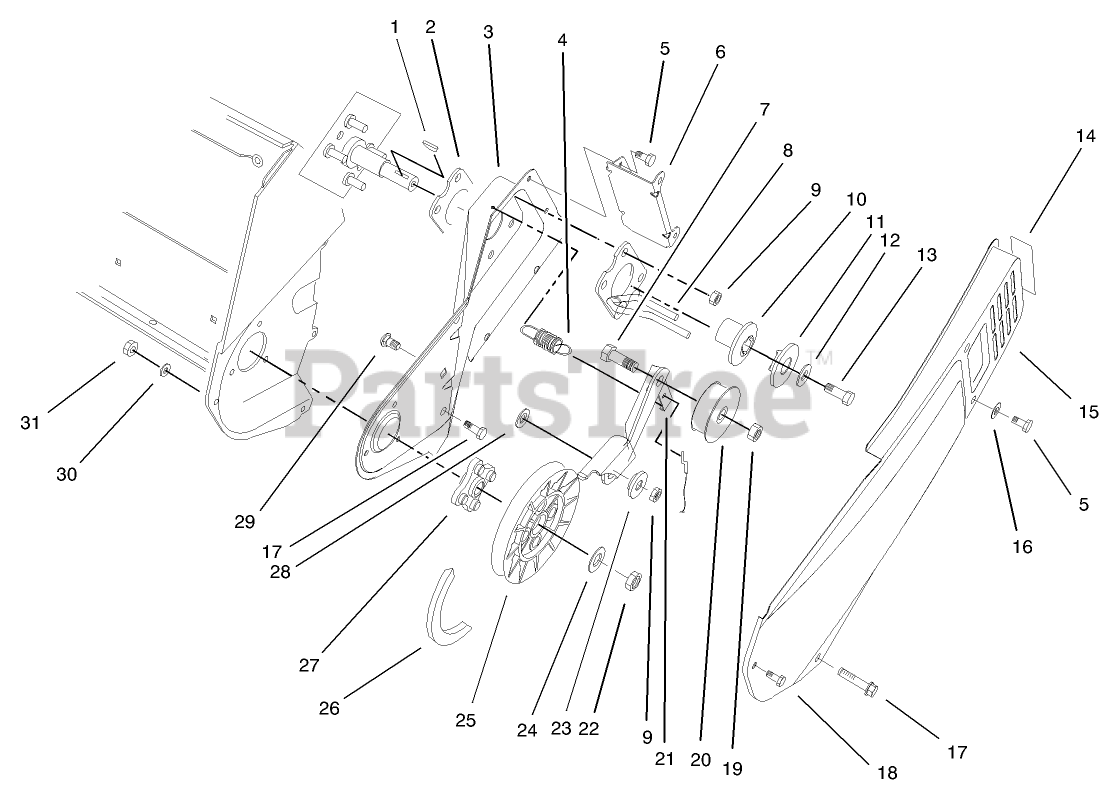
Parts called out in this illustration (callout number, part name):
1	KEY-WOODRUFF
2	PLATE-ENGINE
3	SIDEPLATE-LH
4	SPRING-BRAKE
5	SCREW-HWH
6	BRACKET-COVER, BELT
7	SCREW-HH
8	GUIDE-BELT
9	NUT-LOCK, NI
10	HUB-HALF SHEAVE
11	CAP-HALF SHEAVE
12	WASHER-FLAT
13	SCREW-HH
14	DECAL-HOT
15	COVER-BELT
16	WASHER-FLAT
17	SCREW-PLASTIC
20	PULLEY-IDLER
21	ARM-BRAKE
22	NUT-LOCK, NI
23	BUSHING-IDLER
24	WASHER-FLAT
25	PULLEY-DRIVEN
26	V BELT
28	WASHER
29	SCREW-CARR
30	WASHER-FLAT
31	NUT-LOCK, NI
